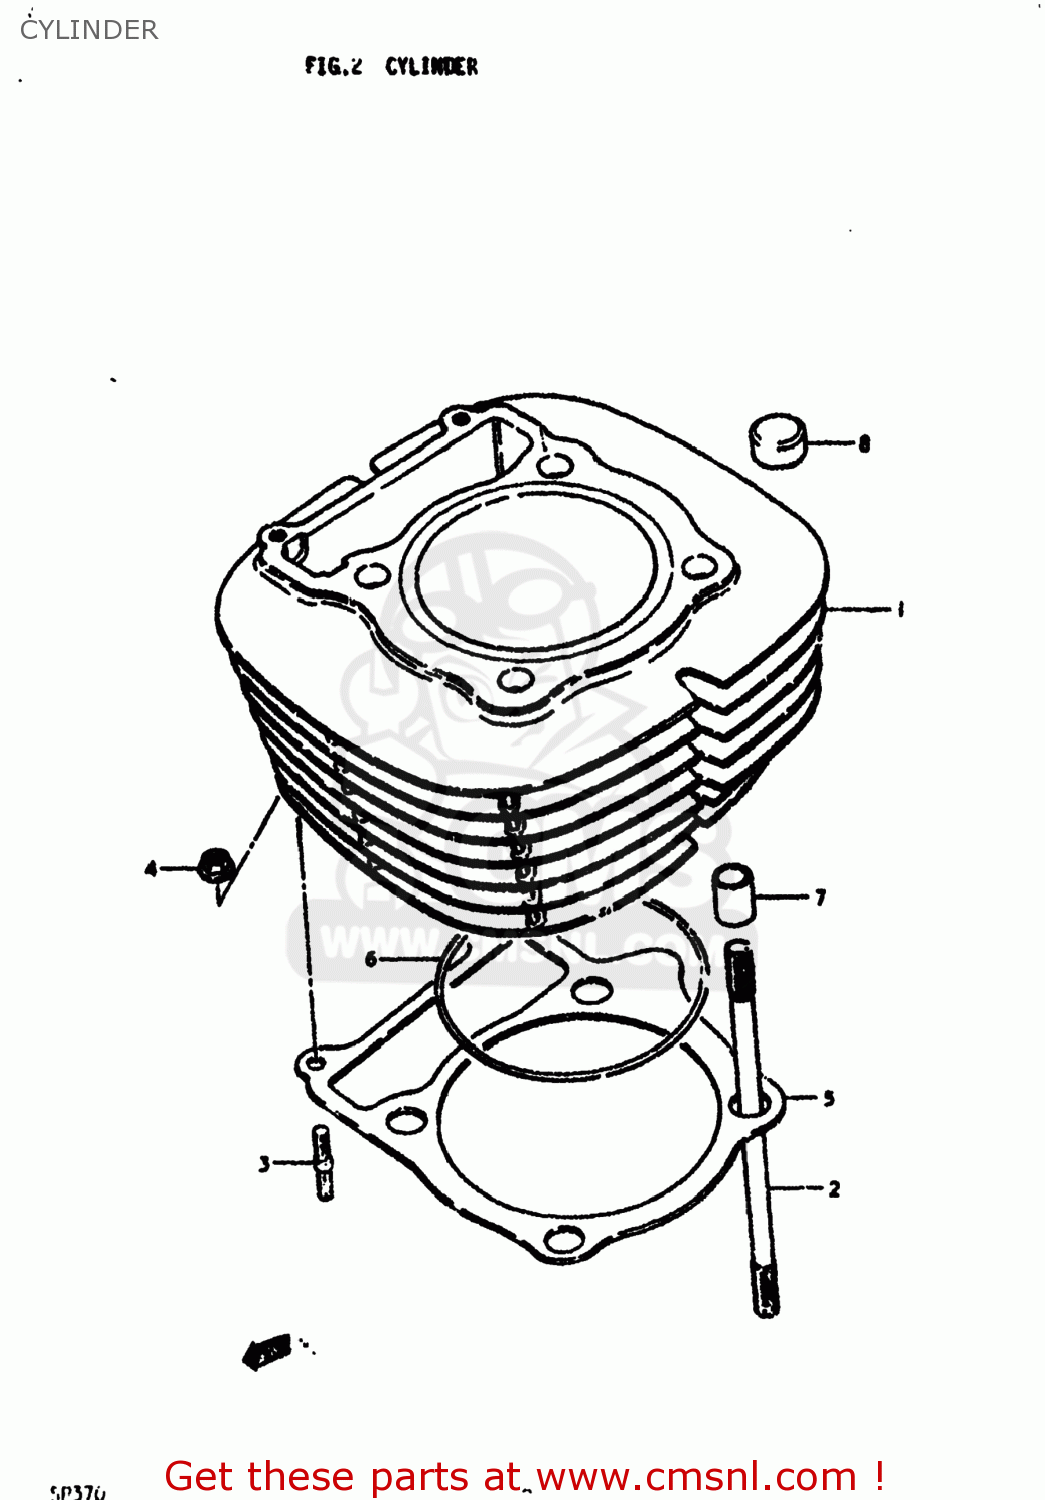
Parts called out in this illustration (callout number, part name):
1	CYLINDER
2	STUD
3	STUD 6X20
4	NUT
5	GASKET,CYLINDER (MCA)
6	O RING(D:2,ID:87)
7	PIN
8	PAD,CYLINDER HEAD
